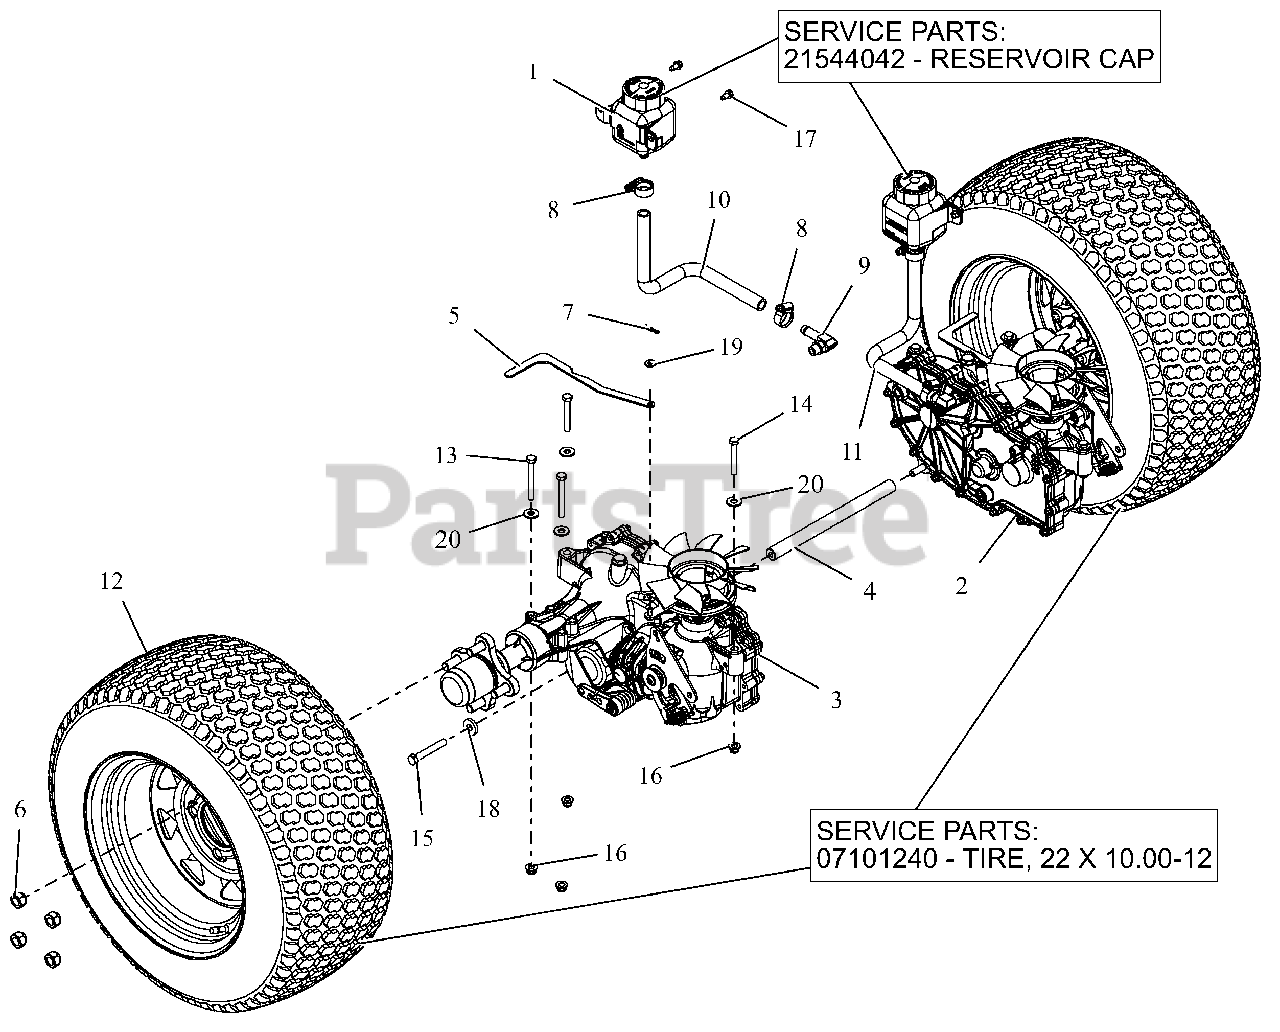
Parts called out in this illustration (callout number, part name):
1	TANK, EXPANSION
1	CAP, HYDRO RESERVOIR REPLAC.
2	TRANSAXLE, ZT3100 LH
3	TRANSAXLE, ZT3100 RH
4	SHAFT, TRANSAXLE SUPPORT
5	BRKT, VALVE DUM
6	WHEEL NUT .500-20 YZ
7	PIN-HAIR, ENDRIES #25 YWZC
8	CLAMP,.88 DIA. HOSE
9	FITTING, HYD (90 DEG)
10	HOSE, FORMED EXPANSION -HD RH
11	HOSE, FORMED EXPANSION -HD LH
12	ASM, WHL/TIRE 22X10.00-12 K500
12	TIRE, 22X10.00-12
13	@BLT-HEX .31-18X2.75 GR5 YWZC
14	@BLT-HEX .31-18X2.25 GR5 YWZC
15	@BLT-HEX .38-16X2.50 GR5 YWZC
16	@NUT-LK-NYL-FLG .31-18 YWZC
17	SCR-TAP .25-20X.50 HWH TR YWZ
18	WSHR-FL-STL .406X1.00X.188 YWZ
19	@WSHR-FL-STL.281X.62X.065 YWZC
20	@WSHR-FL-STL.38X.875X.083 YWZC
